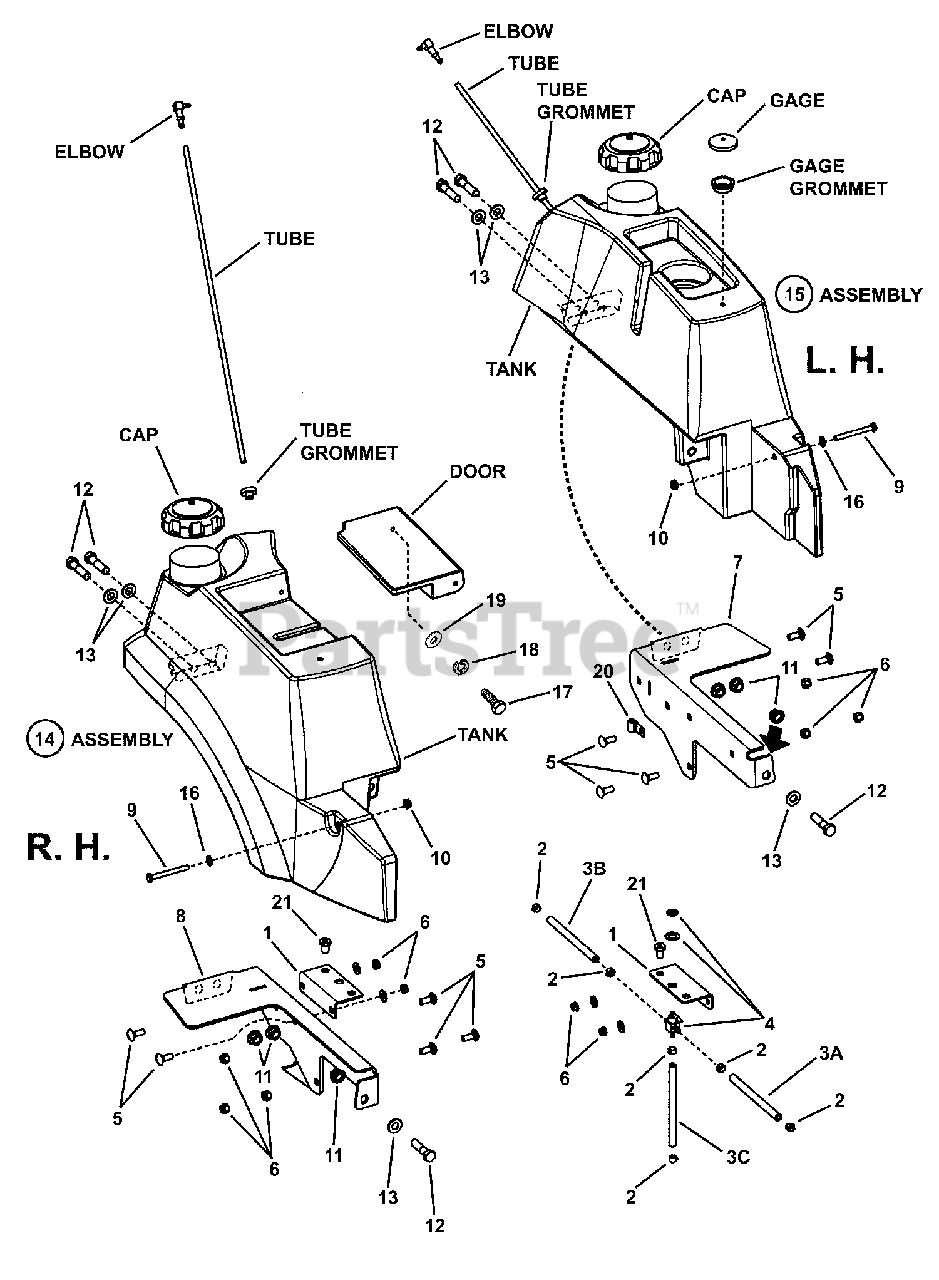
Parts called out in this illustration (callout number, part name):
1	MOUNT, Auxiliary Fuel Valve
2	CLAMP, Fuel Hose
3A	HOSE, 1/4" I.D. x 3'-7.5" Long Fuel (R.H.)
3B	HOSE, 1/4" I.D. x 1'-8" Long Fuel (L.H.)
3C	HOSE, 1/4" I.D. x 1' Long Fuel
4	ASSEMBLY, 3-Way Fuel Valve
5	BOLT, 3/8-16 x 1" Square Neck Carriage, GR 5
6	NUT, 3/8-16 HEX NYLON LOCK
7	WELDMENT, L.H. Tank Bracket
8	WELDMENT, R.H. Tank Bracket
9	SCREW, 5/16-18 x 3" Hex Head Cap, GR 5
10	NUT, 5/16-18 HEX NYLON LOCK
11	NUT, 7/16-14 HEX NYLON LOCK
12	SCREW, 7/16-14 x 2" Hex Head Cap, GR 5
13	WASHER, 1/2" Flat SAE
14	ASSEMBLY, RH Tank
15	ASSEMBLY, LH Tank
16	WASHER, 5/16" Flat
17	SCREW, 1/4-20 x 1-1/4" Hex Head Cap, GR 5
18	WASHER, 1/4" Split Lock
19	WASHER, 1/4" Flat
20	CLIP, Open 3/8" Cushioned
21	WELL-NUT, 1/4-20 x 53/64
